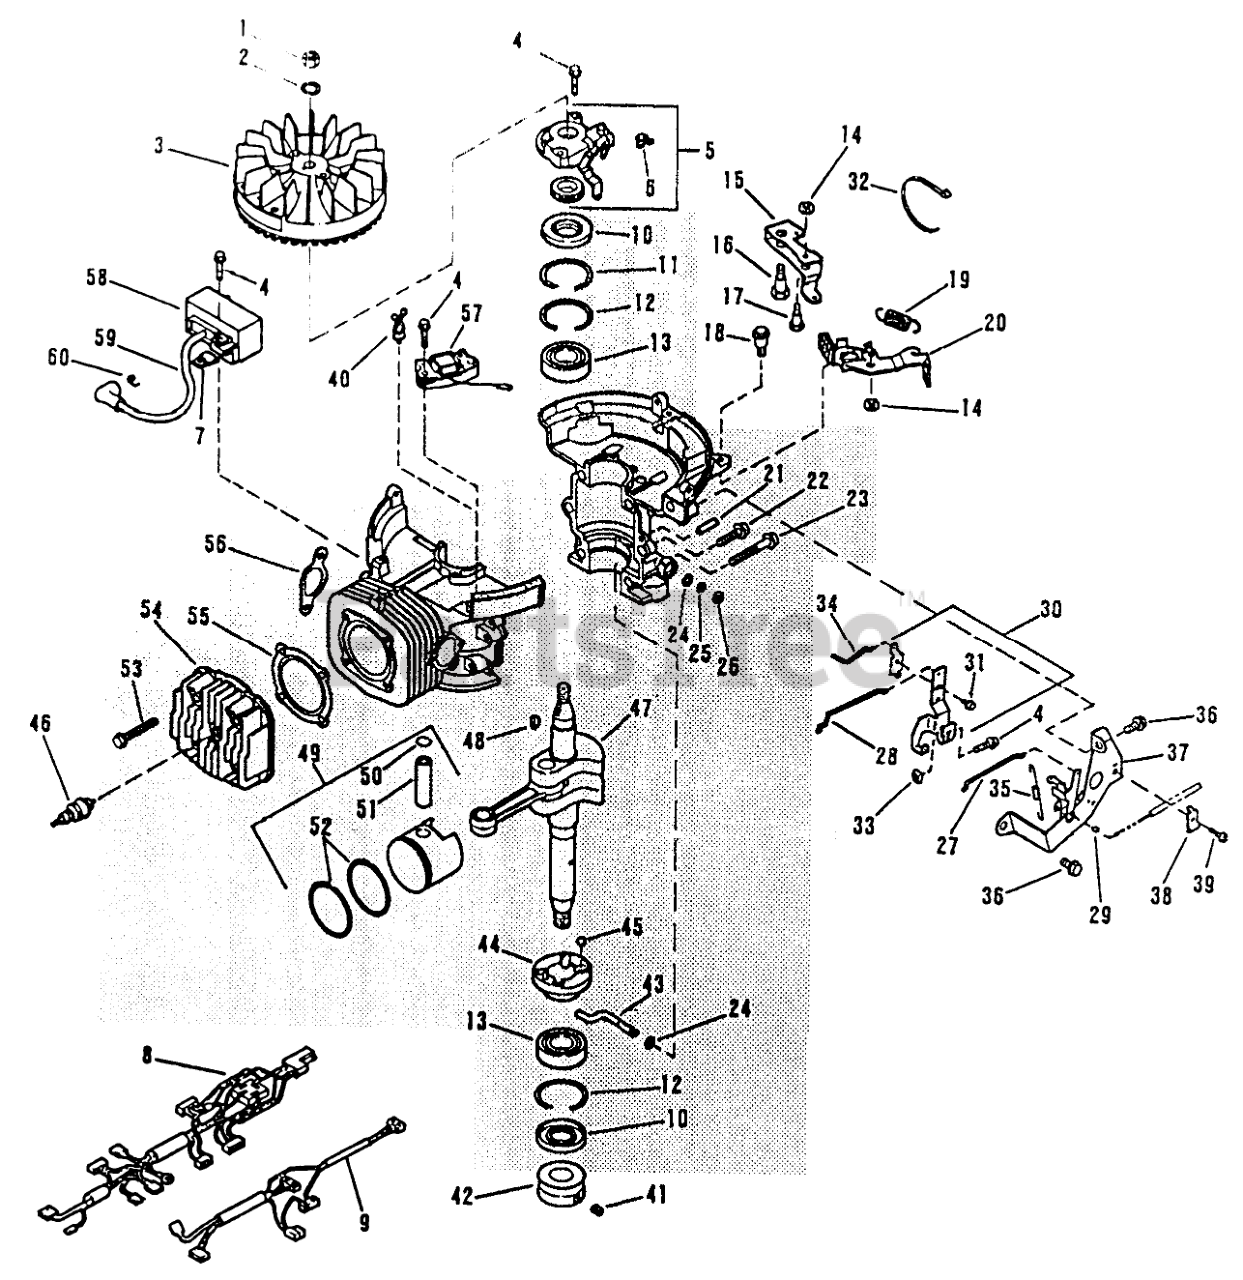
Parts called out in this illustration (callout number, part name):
1	NUT
2	WASHER-LOCK
3	F/WHEEL ALUM SM
3	FLYWHEEL AY SM
4	SCREW
5	OIL PUMP KIT
6	CLAMP SM
7	TERMINAL M
8	Wire Harness
9	WIRE HARNESS SM
10	SEAL - OIL SM
11	RING-RETAINER SM
12	RING RET. SM
13	BEARING-BALL SM
14	LOCKNUT E
15	ACT.BRAKE LVR. SM
16	STUD-SHOULDER SM
17	BOLT-SHOULDER SM
18	BOLT-SHOULDER SM
19	SPRING-BRAKE
20	BRAKE & SWITCH S
21	PIN, TAPER SM
22	SCREW-H.W.HD. F
23	SCREW-HEX W.H. SM
24	WASHER-FLAT SM
25	RING-RETAINING
26	SEAL - OIL SM
27	ROD - CHOKE SM
28	ROD-THROTTLE SM
29	Retainer-Throttle Wire
30	LEVER AY KIT S
31	SCREW V
32	Tie Wrap
33	NUT SM
34	ROD - OIL PUMP SM
35	SPRING-GOV. SM
36	SCREW HEX WASH SM
37	GOVNR BRKT SM
37	BRK&SWITCH AY M
38	CLAMP SM
39	SCREW-CLAMP SM
40	WIRE TIE SM
41	SCREW-SET
42	PULLEY-ENGINE
43	Governor Arm
44	Governor Ramp
45	BALL-GOVERNOR SM
46	Spark Plug
47	C/SHAFT&C.ROD SM
47	CRANKSHAFT SM
48	KEY
49	PISTON&RING AY. S
50	RING-RETAINER SM
51	WRIST PIN SM
52	RING SET S
53	SCREW
54	CYLINDER HEAD SM
55	GASKET-HEAD SM
56	GASKET - EXH SM
57	ALTERNATOR ASM
58	CD Ignition
59	HI-TENS.LEAD SM
